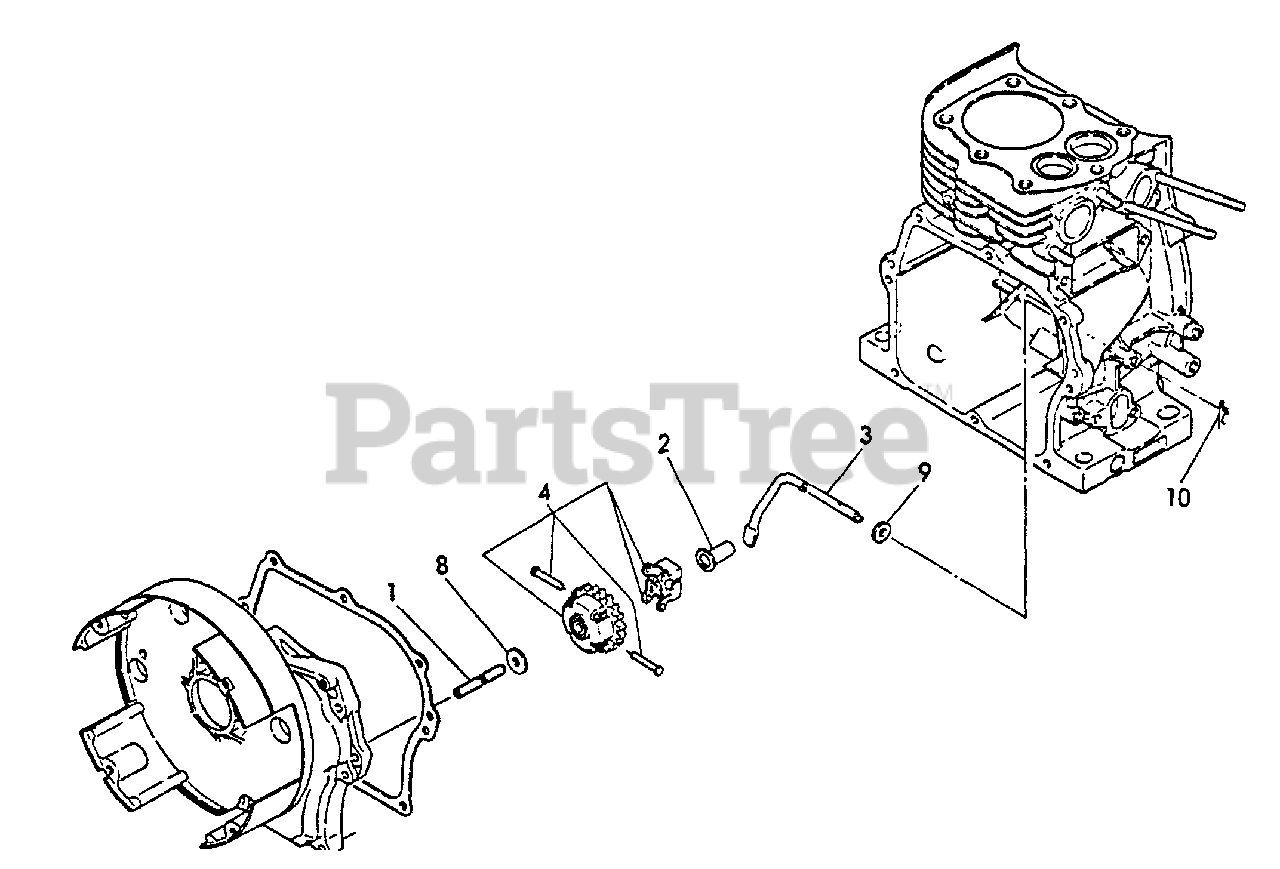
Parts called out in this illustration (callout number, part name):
1	SHAFT, GOVERNOR
2	SPINDLE, GOVERNOR
3	YOKE
4	GOVERNOR GEAR ASSY
8	WASHER
9	WASHER - 6
10	PIN - 6 -- SNAP
